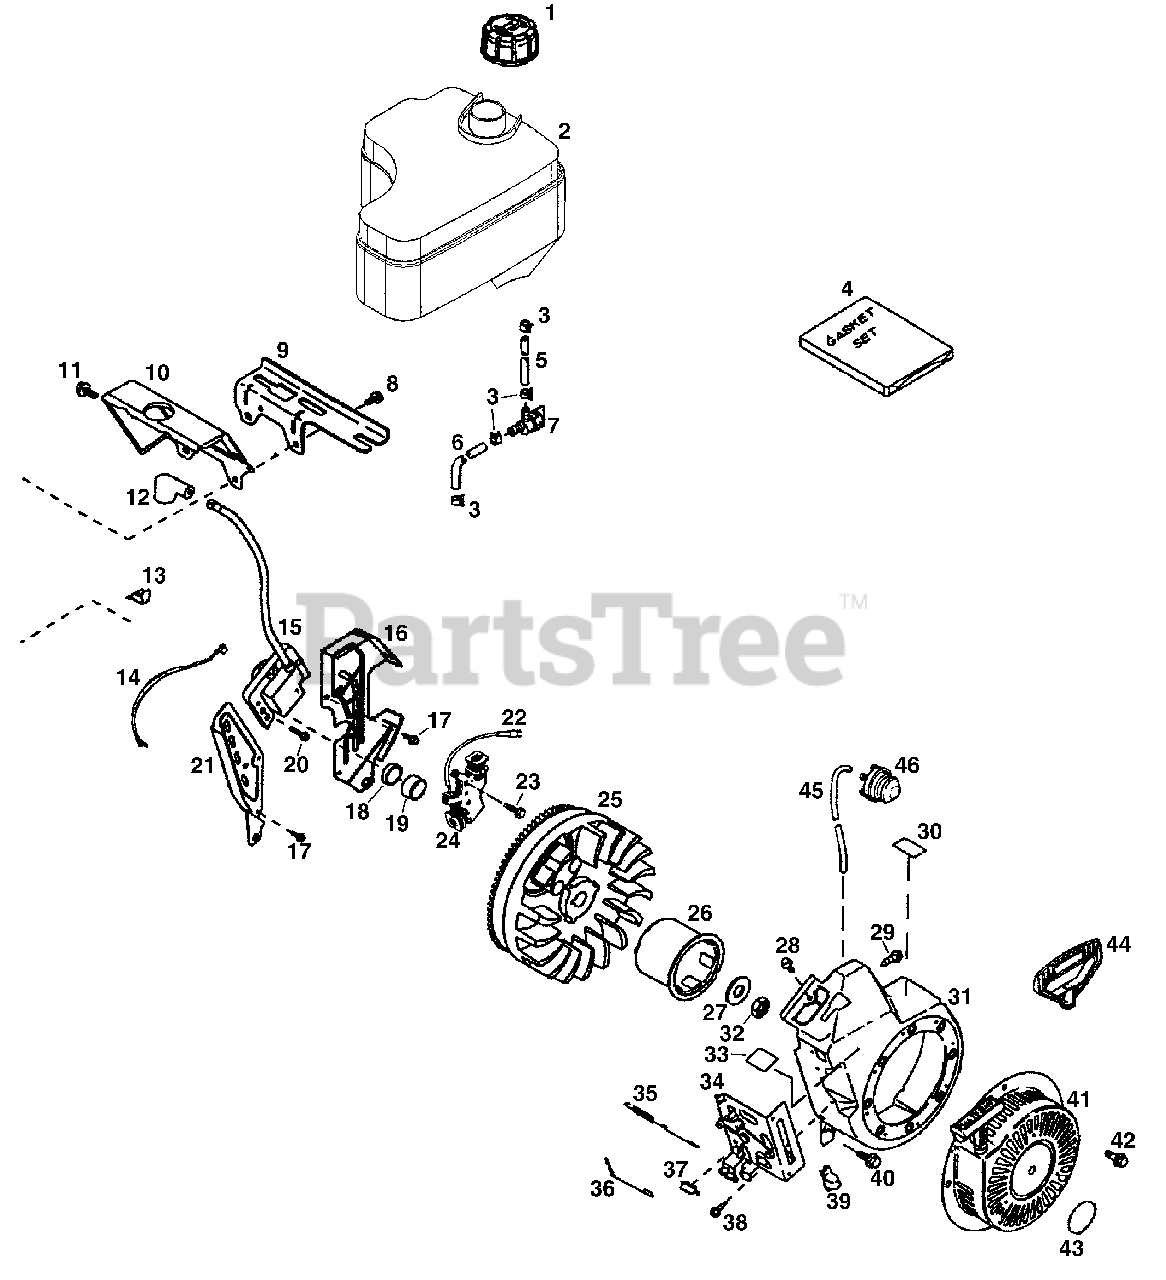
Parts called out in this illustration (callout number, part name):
1	Fuel Cap
2	Fuel Tank
3	Fuel Line Clamp
4	Gasket Set
5	Fuel Line
6	Fuel Line
7	Fuel Shut-Off Valve
8	Screw, 1/4-20 x 7/8".
9	Fuel Tank Bracket
10	Blower Housing Extension
11	Screw, 10-24 x 9/16".
12	Spark Plug Cover
13	Wire Clip
14	Ground Wire
15	Solid State Ignition
16	Air Baffle (Right)
17	Screw, 10-24 x 9/16".
20	Screw, Torx T-15, 15/16".
21	Air Baffle (Left)
23	Screw, 1/4-20 x 3/4".
24	Alternator Coil (18 Watt)
26	Starter Cup
27	Bell Washer
28	Screw, 1/4-20 x 31/64".
29	Screw, 10-32 x 1/2".
30	Lube Decal
31	Blower Housing
32	Flywheel Nut
33	Control Decal
34	Control Bracket
35	Extension Spring
36	Governor Link
38	Screw, 10-32 x 1/2".
39	Control Knob
40	Screw, 1/4-20 x 31/64".
41	Rewind Starter
42	Screw, 1/4-20 x 31/64".
43	Starter Decal
44	Mitten Grip Starter Handle
45	Primer Line
46	Primer Assembly
